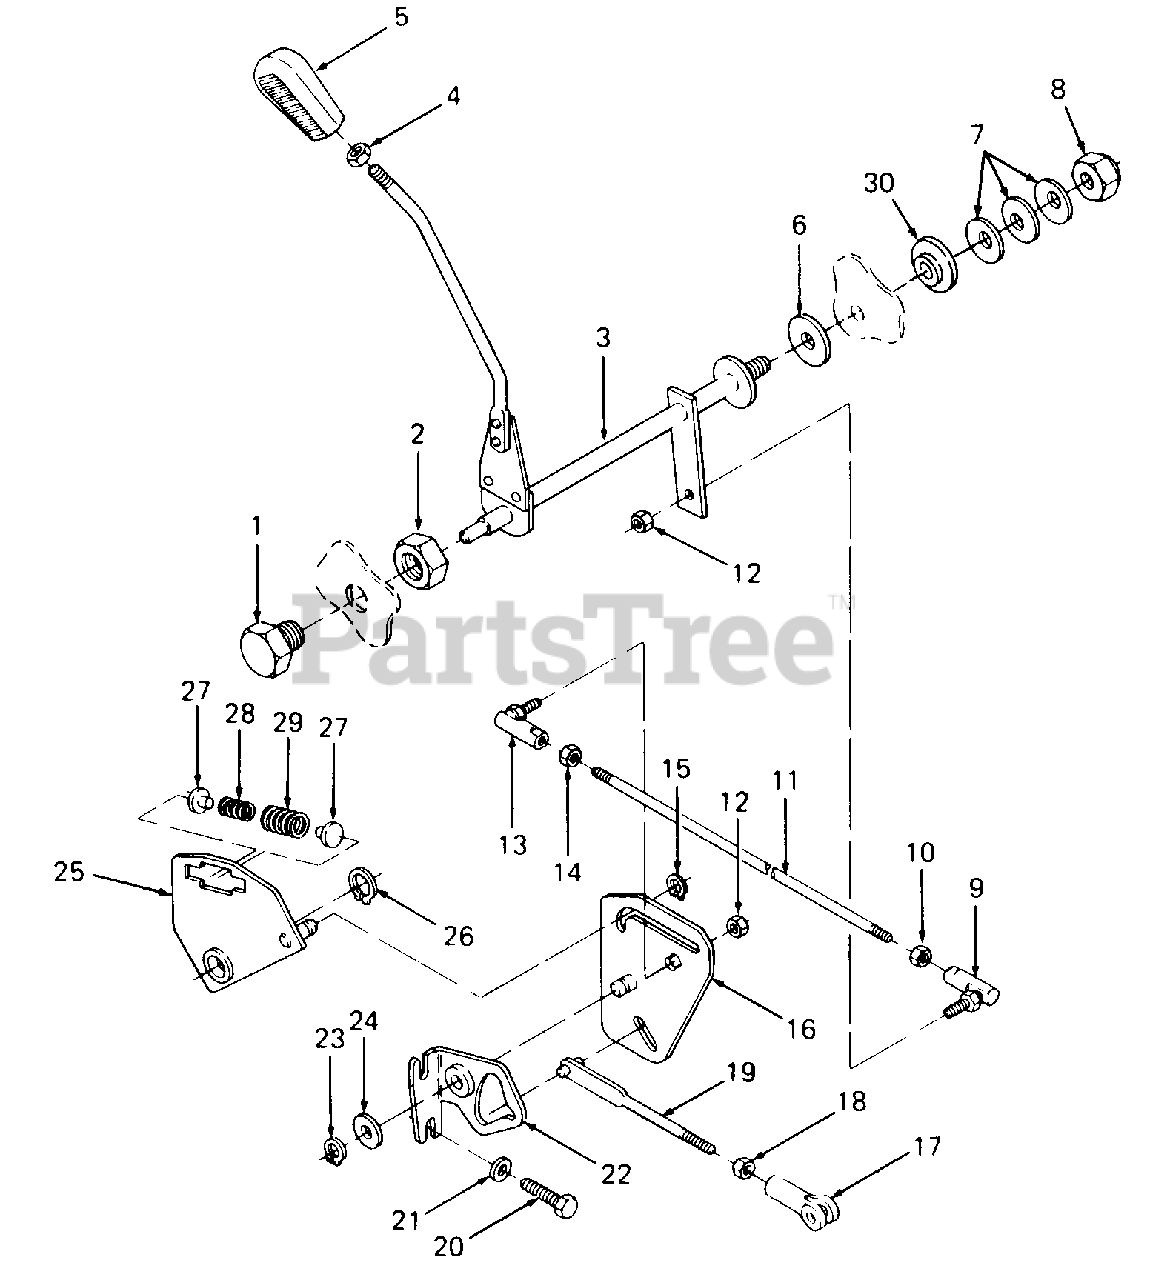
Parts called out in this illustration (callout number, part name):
1	Screw, Rockshaft Bearing, 3/4-16 X .75 Lg
2	Nut, Hex Jam, 3/4-16 GR5
3	Shaft Assy, Cross
4	Nut, Hex Jam, 3/8-16 GR5
5	Knob, Speed Control
6	Disc, Friction
7	Washer, Bell
8	Nut, Hex Top Lock, 1/2-20
9	Ball Joint, 5/16-24
10	Nut, Hex Jam, 5/16-24
11	Rod, Connecting
12	Nut, Hex Patch Lock, 5/16-24
13	Ball Joint, 5/16-24 LH Trd
14	Nut, hex Jam, 5/16-24 LH Trd
15	Ring, Retaining, .375
16	Cam. Control
17	Clevis Adjustment
18	Nut, Hex Jam, 318-24 GR5
19	Rod, Control
20	Screw, Hex Cap, 3/8-16 X 1.5 Lg GR5
21	Washer, Flat, .385 X .87 X..06 Thk HDN
22	Bracket, Cam Pivot
23	Ring, Snap, .500
24	Washer, Flat, .510 X 1.0 X .060 Thk
25	Plate Assy, Damper Spring
26	Ring, Snap, .625
27	Pin, Spring Guide
28	Spring, Compression
29	Spring, Compression
30	Spacer, Shouldered
